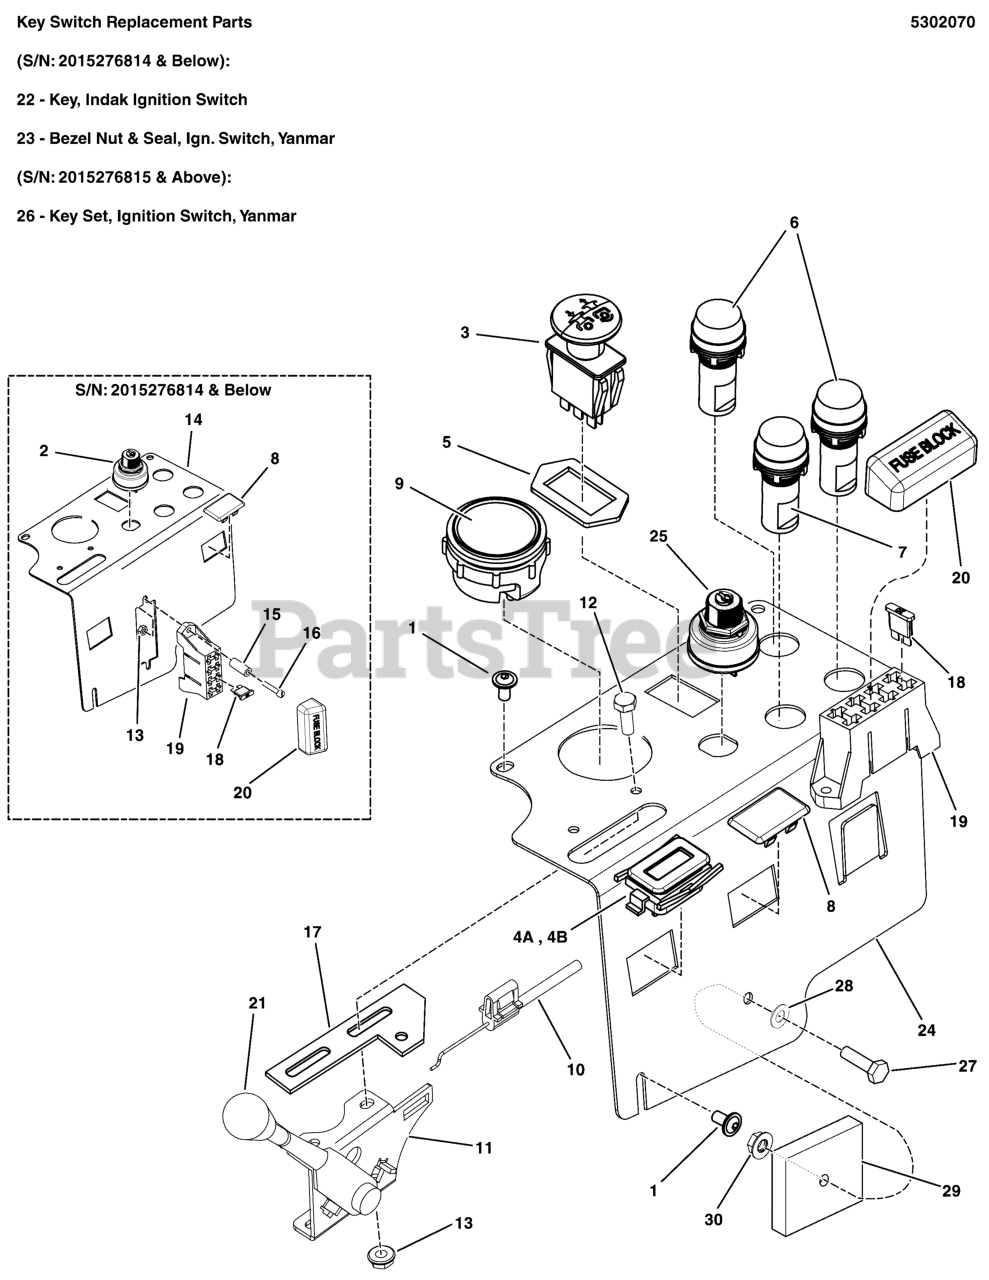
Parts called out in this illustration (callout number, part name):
1	SCREW, 1/4-20 X 1/2 ALLEN BH
2	SWITCH, IGNITION, YANMAR
3	SWITCH, BLADE ENGAGEMENT
5	RING, SWITCH RETAINER
6	LIGHT, WARNING, 22MM RED
7	LIGHT, GLOW PLUG, 22MM AMBER
8	PLUG, .820X1.44 HOLE, BLACK PLASTIC
9	GAUGE, WATER TEMPERATURE
10	CABLE, THROTTLE, 52"
11	LEVER, THROTTLE CONTROL, HEAVY-DUTY
12	SCREW, #10-24 X 3/4 ROUND PHILLIPS
13	NUT, #10-24 HEX NYLON LOCK
14	PANEL, CONTROL - BLK
15	SPACER, .20 X .38 X 1.75, YZ
16	SCREW, 10-24 X 2-1/2, RD HD PHILLIPS, CZ
17	PLATE, THROTTLE STOP
18	FUSE, ATO, 20 AMP
19	FUSE BLOCK
20	COVER, VINYL FUSEBLOCK
21	THROTTLE CONTROL HANDLE/KNOB
22	KEY SET, INDAK IGNITION SWITCH
23	BEZEL NUT & SEAL, IGN.
24	CONTROL PANEL - BLK
25	IGNITION SWITCH, SEALED
26	KEY SET, Ignition Switch, 3 position (SV)
27	BOLT, 1/4-20 X 1-1/2, GD5
28	WASHER, 1/4 SAE
29	MODULE,DCK SHUT OFF W/DELY,175/2500/5100
30	NUT, 1/4-20 HEX NYLOCK FLANGE
